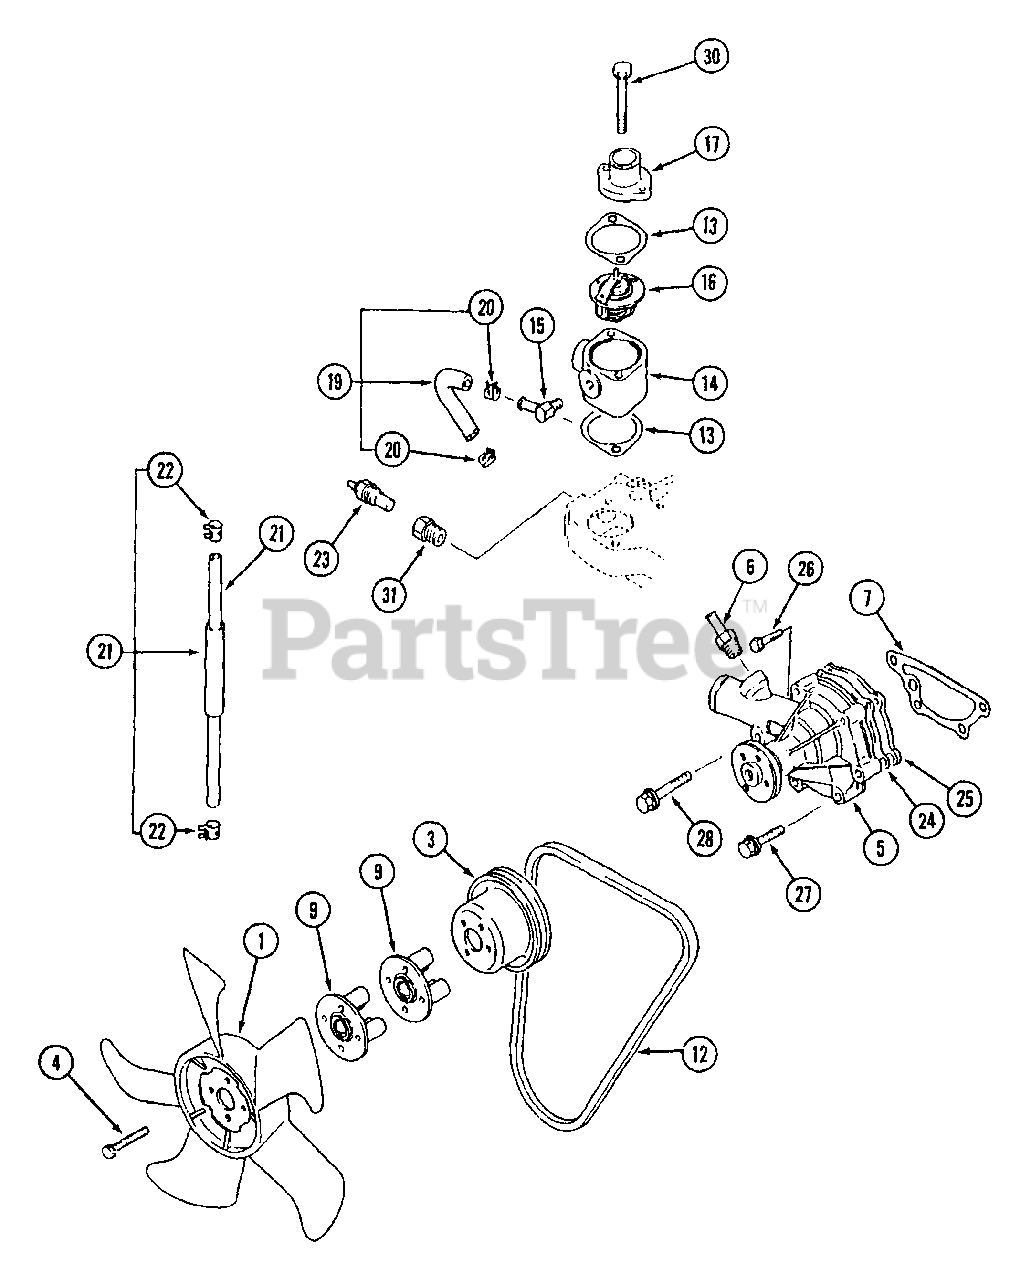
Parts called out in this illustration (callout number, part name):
1	Fan, Cooling
3	Pulley, Water Pump
4	Bolt,
5	Water Pump Ass'y.
6	Nipple, Base
7	Gasket, Water Pump
9	Spacer, Fan
13	Gasket
14	Fitting, Thermostat
15	Joint, Water Hose
16	Thermostat
17	Fitting, Water Outlet
19	Hose Ass'y., Water
21	Hose Ass'y., Water Drain
23	Unit, Thermo
24	Gasket, Water Pump
25	Plate, Water Pump
26	Bolt,
27	Bolt,
28	Bolt,
30	Bolt,
31	Joint, Thermo Gauge Unit
